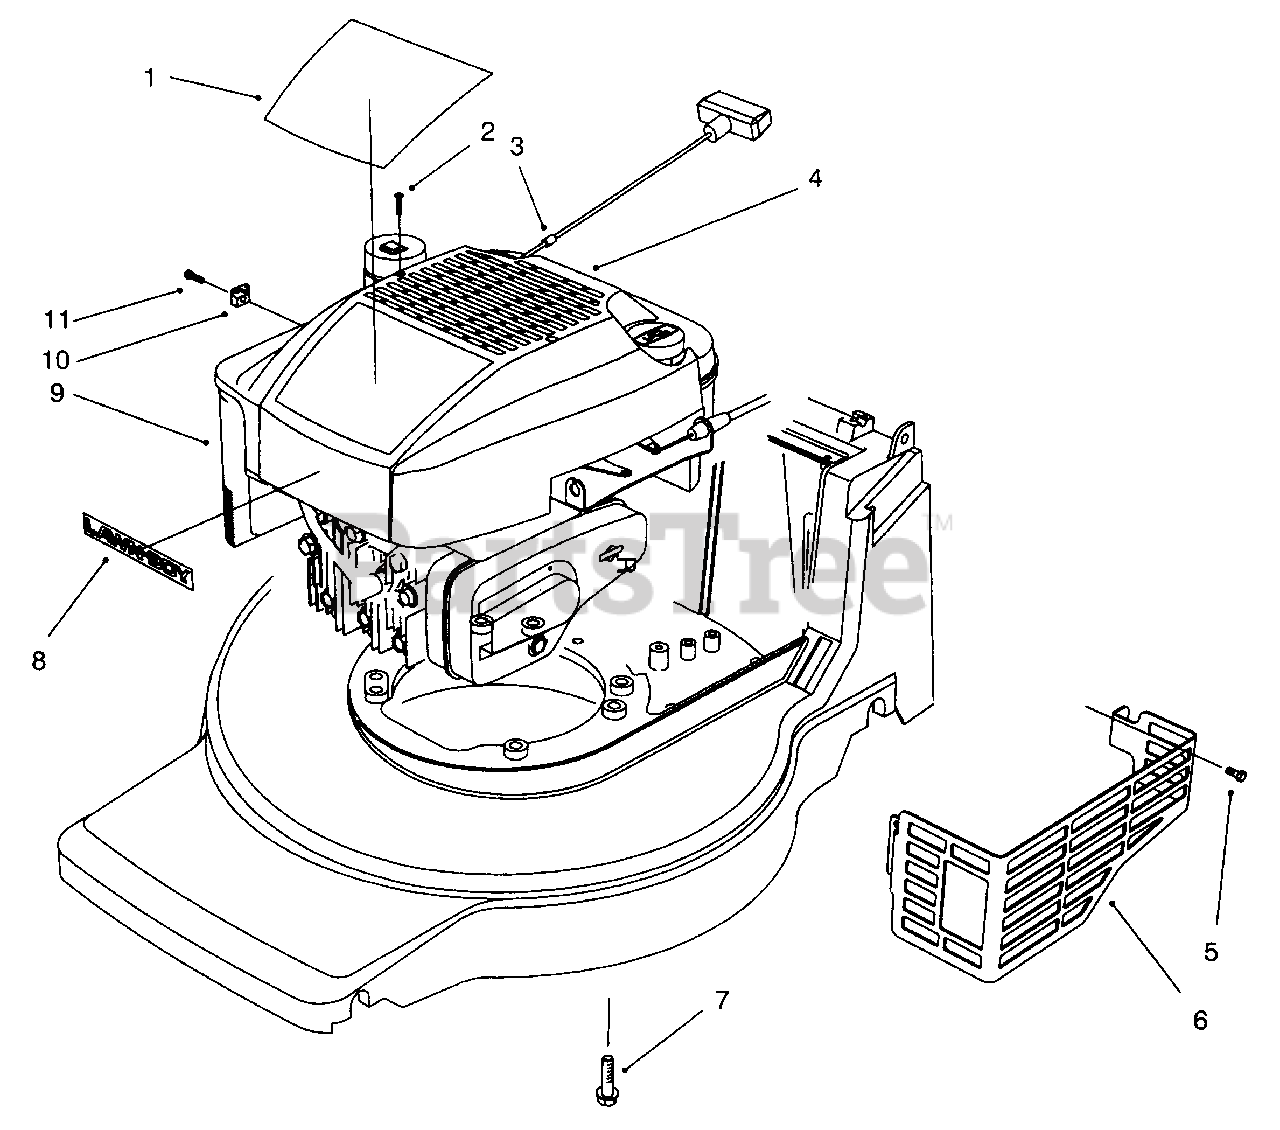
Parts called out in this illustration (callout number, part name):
1	Decal-Recoil
2	Screw-Mounting
3	Stop-Rope
4	Cover-XTE
5	Screw-Hex Washer Head Thread Forming
6	Shield-Muffler
7	Screw-Tapping
8	Decal-Shroud
9	Engine
10	Clamp-Casing
11	Screw-Clamp
